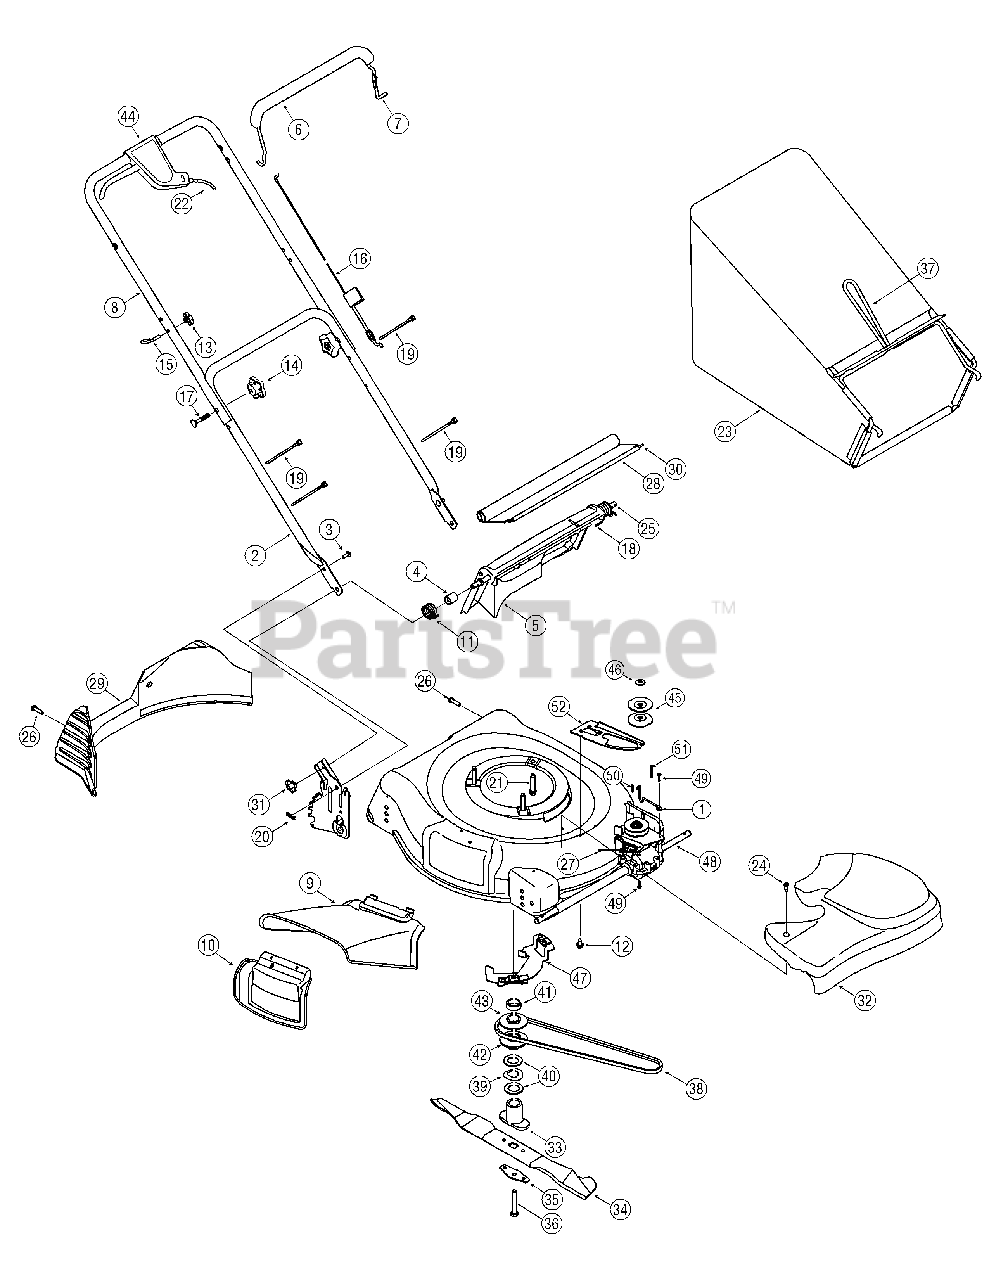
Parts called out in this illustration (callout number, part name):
1	Belt Keeper Wire
3	Carriage Bolt 1/4-20
4	Spacer.375 x.50 x 1.02" Lg.
5	Rear Discharge Door
6	Deluxe Cover
10	Mulch Plug Complete
11	Torsion Spring - RH
12	Screw, 1/4-14 x .625
13	Handle Knob
14	Handle Knob
16	Control Cable - 37.25"
17	Carriage Bolt 5/16-18 x 2.0
18	Torsion Spring - LH
19	Cable Tie
20	Cotter Pin
21	Self-Tapping Sems Screw
22	Drive Cable
23	Grassbag Assembly
24	Shoulder Screw # 12 -24
25	Pivot Rod
26	Screw, 1/4-15 x 1.25
27	Extension Sprg., .350OD x 3.07 lg
28	Rear Trailing Shield
29	Rear Baffle
30	Wire
31	Wing Nut
32	Transmission Cover
33	Blade Adapter
34	21" Mulching Blade
35	Blade Bell Support
36	Hex Screw 3/8-24 x 2.50
38	V-Belt
39	Sprg. Washer, 1.005 x 1.825
40	Flat Washer, 1.00 x 1.75 x .107
41	Slv. Spacer, 25mm x 1.375 X .620
42	Key Half Pulley, 25mmID x .262 OD
43	Upper Half Pulley, 25mmID x .262 OD
44	Control Lever Assembly
45	Pulley, 3.82 x .313 x .68
46	Bell Washer, .325 x .930 x .45
48	Transmission Assembly
49	Torx Screw
50	Spirol Pin
51	Dowel pin
